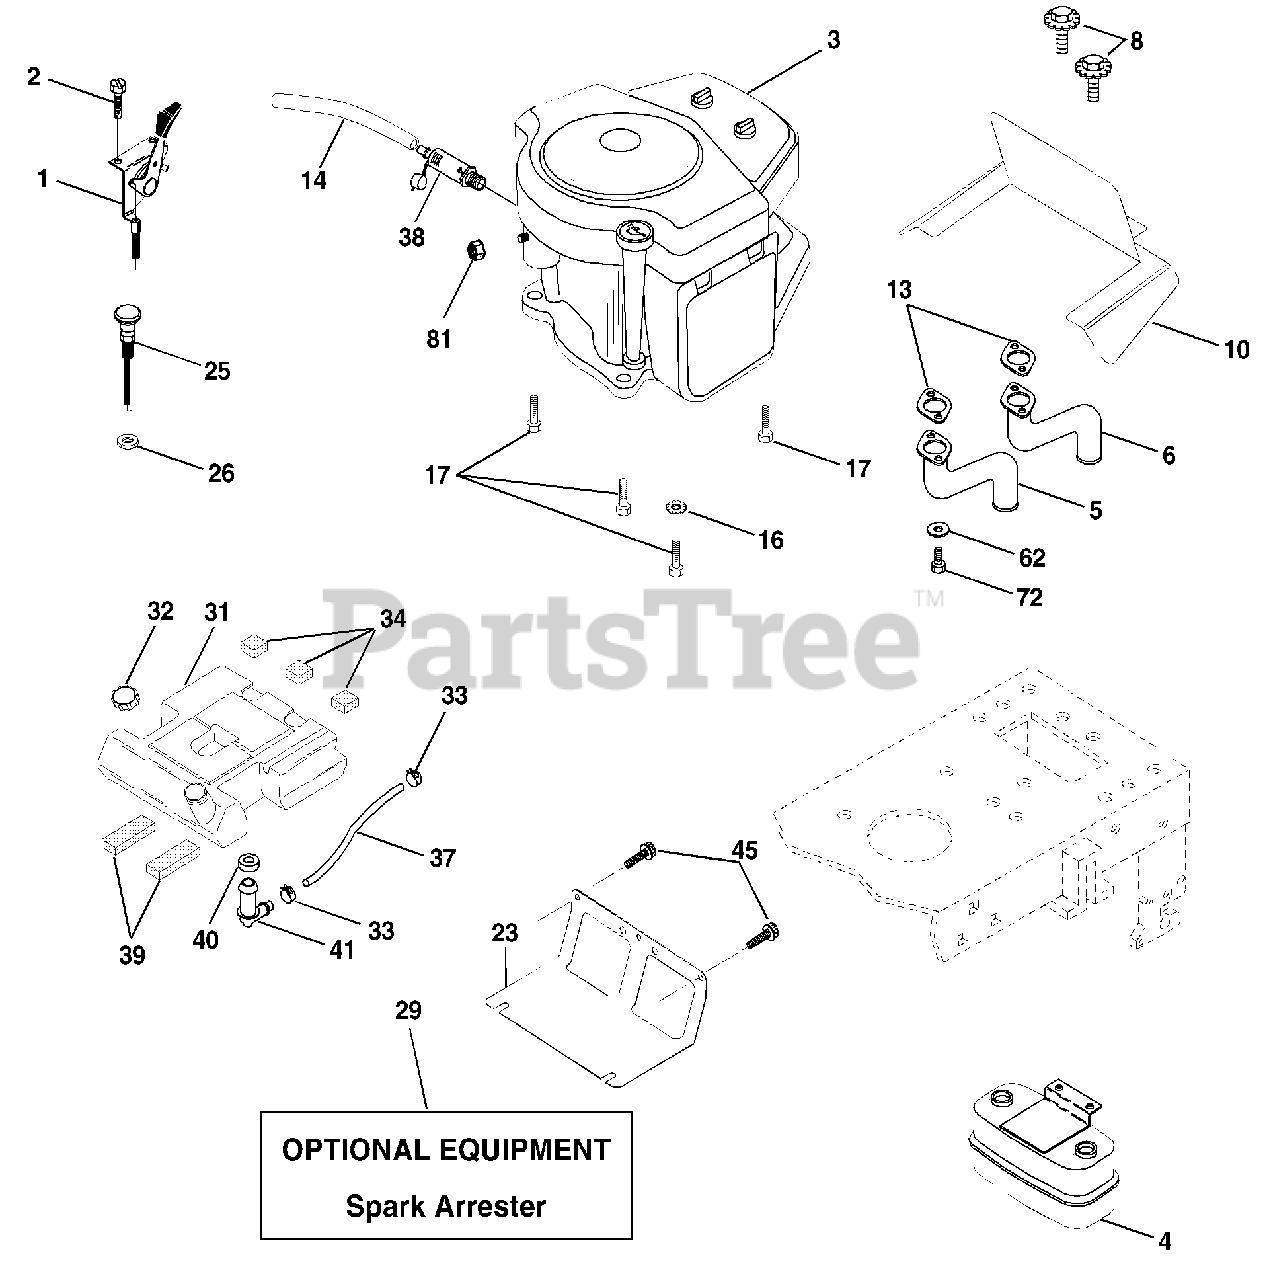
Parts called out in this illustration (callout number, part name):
1	Control Th/Flag 180 LH 36"
2	Screw Hex Thd Cut 1/4-20 x 5/8 T
4	Muffler Asm Twin Lo-Tone
5	Pipe Exhaust LH Intek
6	Pipe Exhaust RH Intek
8	Bolt 5/16-18 UNC x 3/4 w/Sems
10	Shield Browning Intek II
13	Muffler Gasket
14	Nipple Pipe 3/8 Npt X 4-1/2"
15	Elbow Std 90 Degree 3/8-18 Npt
16	Washer Lock Ext Tooth 3/8
17	Screw Thdrol 3/8-16 x 1-1/2
23	Shield Heat
25	Choke Control 37"
26	Nut, Keps 3/8-24 UNF
29	Kit Spark Arrestor (Flat Scrn)
31	Tank Fuel 3 50 Rear YTGT
32	Cap Asm Fuel W/sym Vented
33	Clamp Hose Black
34	Pad, Spacer
37	Line Fuel
38	Plug Oil Drain
39	Pad, Idler
40	Bushing
41	Stem Tank Fuel
45	Screw Hexwsh Thdr 3/8-16 x 3/4
62	Washer Lock 5/16
72	Screw Hex Hd Cap 5/16-18 x 3/4
81	Nut Keps Hex 1/4-20 UNC
